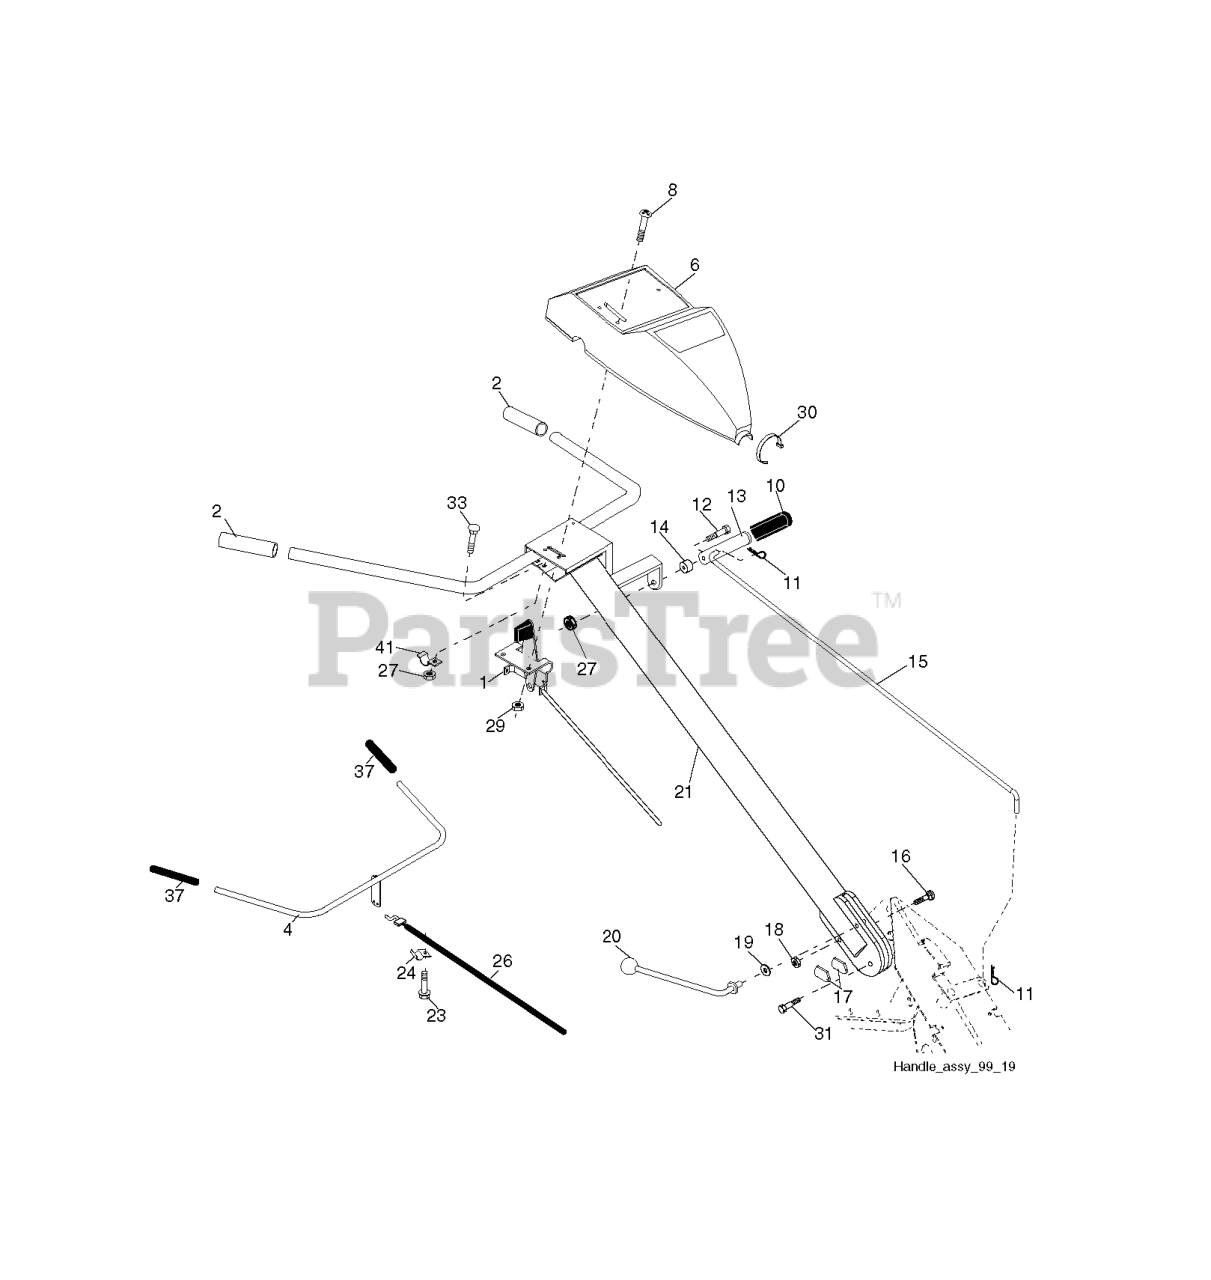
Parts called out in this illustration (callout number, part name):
1	CONTROL.THROTTLE
2	GRIP.1X5.06
4	CONTROL BAR ASSY
6	RP CONTROL PANEL
8	SCREW.PNHD.10-24
10	GRIP T
11	RETAINER M
12	SHOULDER BOLT ST
13	HANDLE.SHIFT.TILLER
14	GROMMET.RUBBER.CRT.TILLER
15	SHIFT ROD CRT
16	BOLT D
17	LOCK.HANDLE.CRT
19	WASHER CRT
20	LEVER.LOCK.CRT
21	REPL BY 532 1805-17
23	TAPPING SCREW
24	CONDUIT.CLIP.PLATED
26	CABLE.CLUTCH
27	NUT T
29	NUT **
30	TIE CABLE CRT
31	BOLT.PIVOT
37	GRIP BAR CRT(1)
41	CLAMP.BAR.CRT.BLACK
